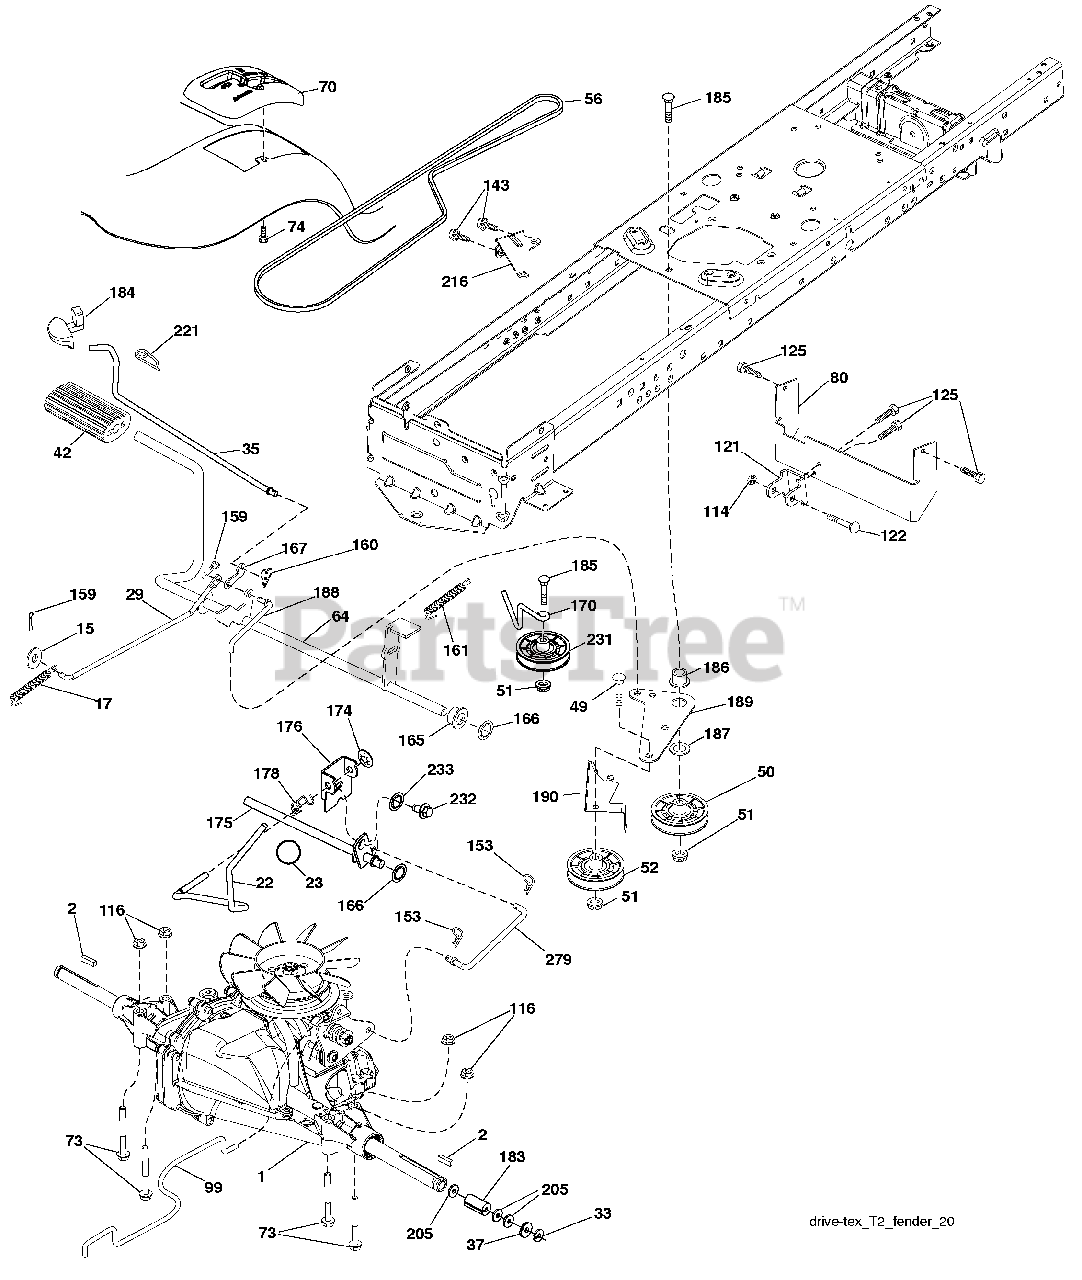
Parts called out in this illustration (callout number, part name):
2	Key Square
15	Washer 13/32 x 13/16 x 16 Ga.
17	Spring, Brake
22	Rod Shift
23	Knob
29	Rod, Brake
33	Ring E
35	Rod, Brake, Park
37	Washer 25/32 x 1-1/4 x 16 Ga.
42	Cover, Foot Pedal
49	Bolt
50	Pulley Idler Flat
51	Lock Nut 3/8-16
52	Idler V-Groove 910" Offset
56	V-Belt, Drive
64	Shaft Asm. Pedal Brake Control
70	Console
73	Bolt Hex 5/16-18 Gr. 5
74	Screw 1/4 x 1/2
80	Strap Torque
99	Rod Spring Bypass
114	Nut Lock 5/16-18 unc
116	Nut Lock Hex Flange 5/16-18
121	Bracket Strap Torque
122	Bolt 5/16-18 x 2.50
125	Screw 5/16-18 x 3/4
143	Screw 5/16-18 x 1/2
153	Retainer Spring 1"
159	Pin Cotter 1/8 x 3/4
160	Retainer Clip
161	Spring, Return, Clutch
165	Bushing
166	Nut Push .625
167	Latch Brake Parking
170	Keeper V-Idler
174	Nut Push
175	Shaft Asm Shift
176	Arm Clevis Rod Shift
178	Spring Shift
183	Spacer Axle
184	Handle Parking Brake
185	Bolt
186	Spacer Retainer
187	Washer
188	Link Clutch Ground Drive
189	Bellcrank Ground Drive
190	Keeper Bellcrank Ground Drive
205	Washer 25/32 x 1-5/8 x 16 Ga.
216	Bracket Pulley Idler
221	Retainer Spring Clip Handle
231	Idler V-Groove 1.688" Offset
232	Bolt 7/16-14 x 1 Gr 5
233	Washer Serrated
279	Link Shift
